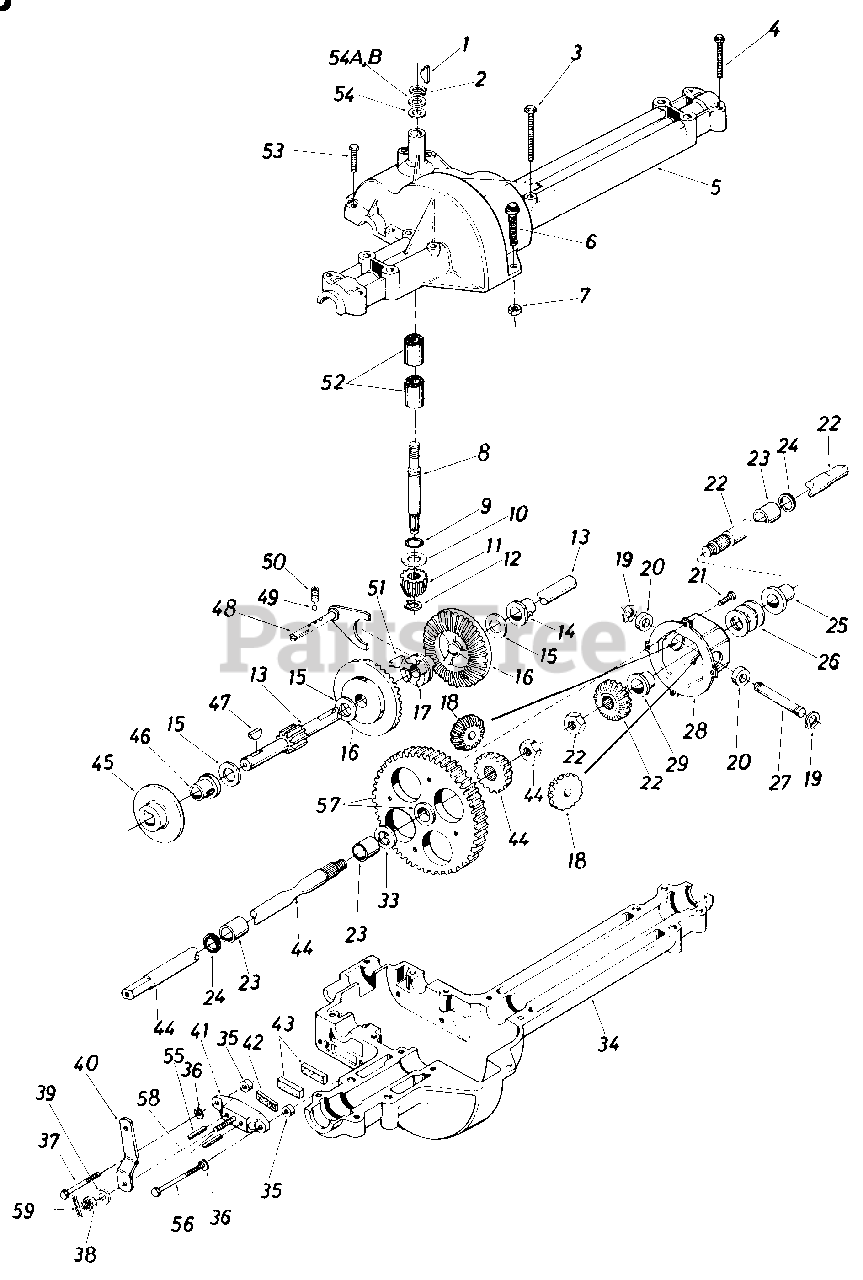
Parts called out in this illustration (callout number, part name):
1	#4 Hi-Pro Key 3/32 x 5/8" Dia.
2	Snap Ring .625" Shaft
3	Hex Bolt 1/4-20 x 1.75" Lg.
4	Hex Bolt 5/16-18 x 2.5"
5	Upper Housing
6	Hex Fl-Bolt 1/4-20 x .88" Lg.'
7	Hex Nut 1/4-20 Thd.
8	Input Shaft
9	Square Seal 5/8" I.D.
10	Thrust Washer 5/8" I.D. x 1.25" O.D.
11	Pinion Input 14T
12	Retaining Ring 7116" Ext.
14	Flange Brg. 518" I.D. x 3/4" Lg.*
15	Fl-Wash.
16	Bevel Gear 42T
17	Clutch Collar
18	Miter Gear 15T
19	Snap Ring
20	Thrust Bearing 1/2" I.D. x 1.0" O. D.
21	Pan Head Scr. '/4-20 x .50" Lg. w/Patch
22	Axle R.H. Ass'y.-Kit
23	Sleeve Bearing 3/4" I.D. x 1.0" Lg.
24	Oil Seal 3/4" I.D.
25	Flange Bearing 3/4" I.D. x 15/16" Lg.
26	Fl-Wash. .760" I.D. x 1.49" O.D.
27	Cross Shaft
28	Differential Housing Ass'y.
33	Fl-Wash. .760" I.D. x 1.49" O.D.
34	Lower Housing
35	Spacer .53" O.D. x 3/8" Lg.
36	L-Wash. 1/4" I.D.
37	Hex Bolt 1/4-20 x 1.50" Lg. (Grade 5)
38	Castle Nut 5/16-24 Thd.
39	Fl-Wash. .344 I.D. x .875" O.D.
40	Actuating Arm
42	Puck Plate
43	Brake Puck
44	Axle L.H. Ass'y.-Kit
46	Flange Bearing 5/8" I.D. x 15/16" Lg.
47	Woodruff Key 3/16 x 5/8 HT
48	Shift Fork Ass'y.
49	Ball Detent .250" Dia.
50	Spring Detent
51	#9 Hi-Pro Key 3/16" x 3/4" Dia. HT
52	Needle Brg. 5/8" I.D. x '/2'
53	Hex Bolt t/4-20 x 1.00" Lg.
54	Fl-Wash. 5/8" I.D. x .030
54A	Fl-Wash. 5/8" I.D. x .040
55	Actuating Pin 5/16" Dia.
56	Hex Bolt 1/4-20 x 2.50" Lg.- 0 (Grade 5)
57	Differential Gear 72T Ass'y. w/Bearing
58	Sq. Hd. Bolt 5/16-24 Thd.
59	Cotter Pin 3/32" Dia. x .50" Lg.
